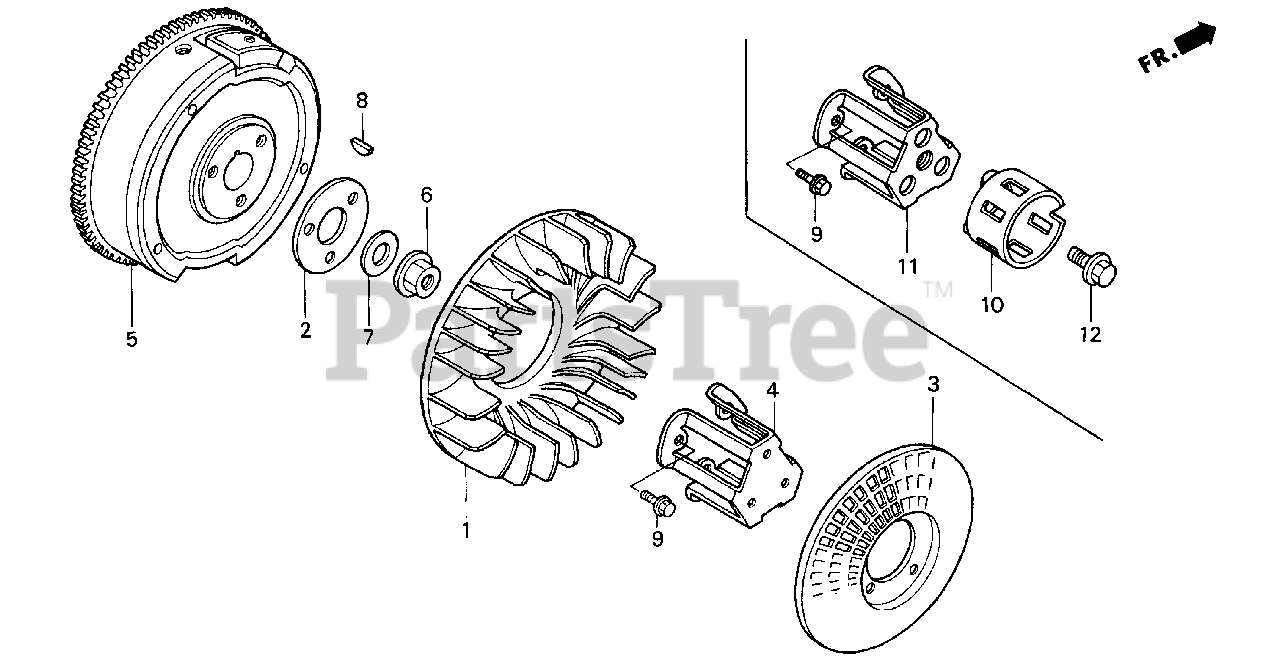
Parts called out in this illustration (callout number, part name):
1	FAN, COOLING
2	PLATE, COOLING FAN SETTING
3	GRID, SCREEN (P.T.O.)
4	HOLDER, SCREEN GRID
5	FLYWHEEL
6	NUT, FLANGE (20MM)
7	WASHER (20MM)
8	KEY, SPECIAL WOODRUFF (25X18)
9	BOLT, FLANGE (8X16)
